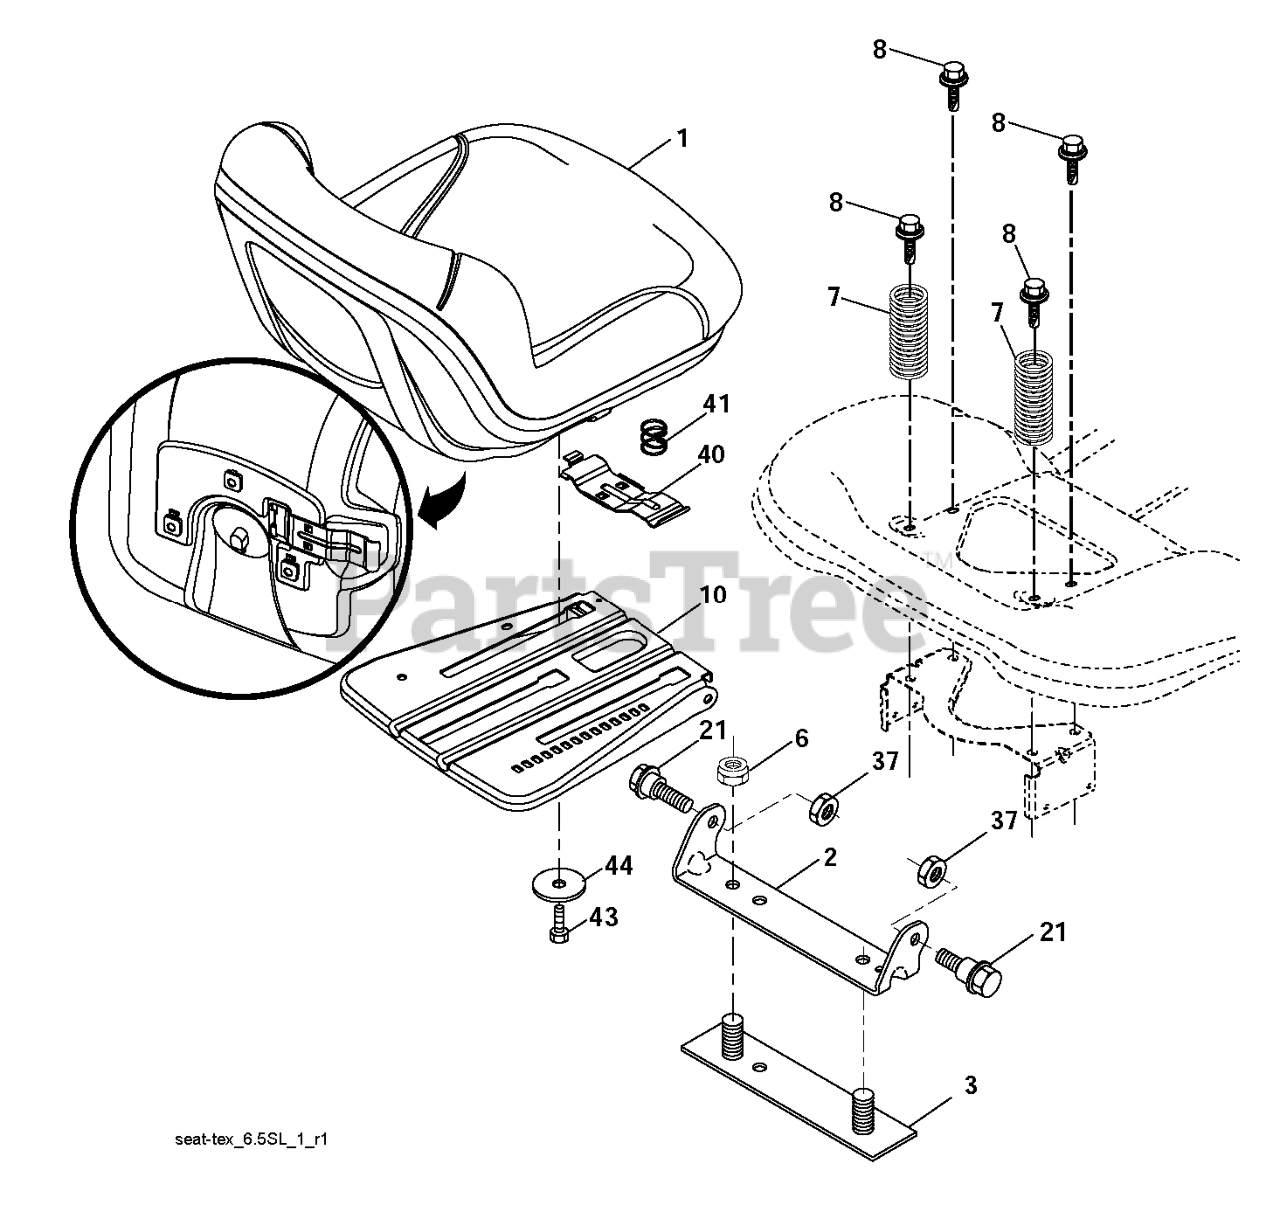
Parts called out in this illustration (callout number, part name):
1	RP SEAT.TH130.GRY.MILSCO.
2	BRKT.PIVOT.FENDER
3	STRAP
6	NUT
7	SPRING COMPRESSION
8	BOLT.5/16-18UNCX3/4 W/SEMS.BLK
10	PAN.ASM.SEAT.3PT
21	BOLT.SHOULDER.5/16-18
37	NUT.71038.31-18.HEX.NYLOCK
40	HANDLE.SLIDE.SEAT.TEX.BLACK
41	SPRING.LATCH.SEAT.TEX
44	WASHER 13/32 X 2-3/8 X 12GA
